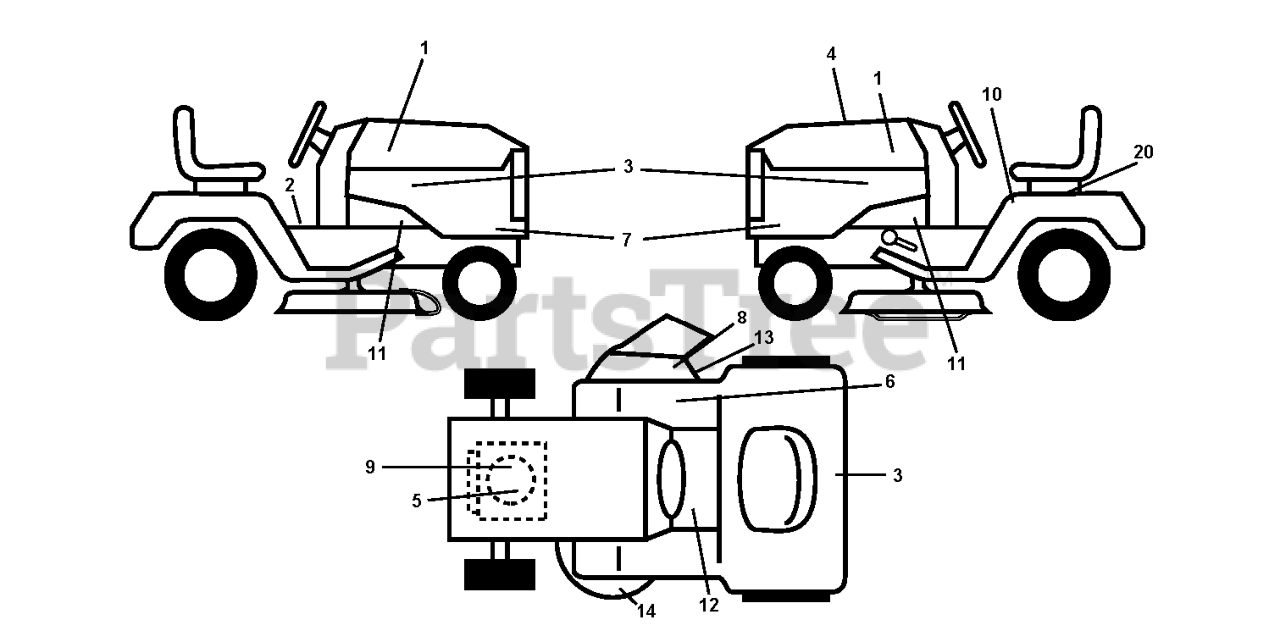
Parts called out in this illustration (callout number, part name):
2	DECAL PARK BRAKE
3	DECAL.HOOD.LOGO.ORANGE.HUSQVAR
5	DECAL
6	Decal, Fender 100 DB/CE
8	DECAL.INTERNATIONL.CUTFINGER
9	Decal, BS Engine
10	LABEL
12	DECAL
13	DECAL, DEFLECT WARNING
14	DECAL.V-BELT.SCHEMATIC.36/38/9
20	DECAL BTRY SYMBOLS
